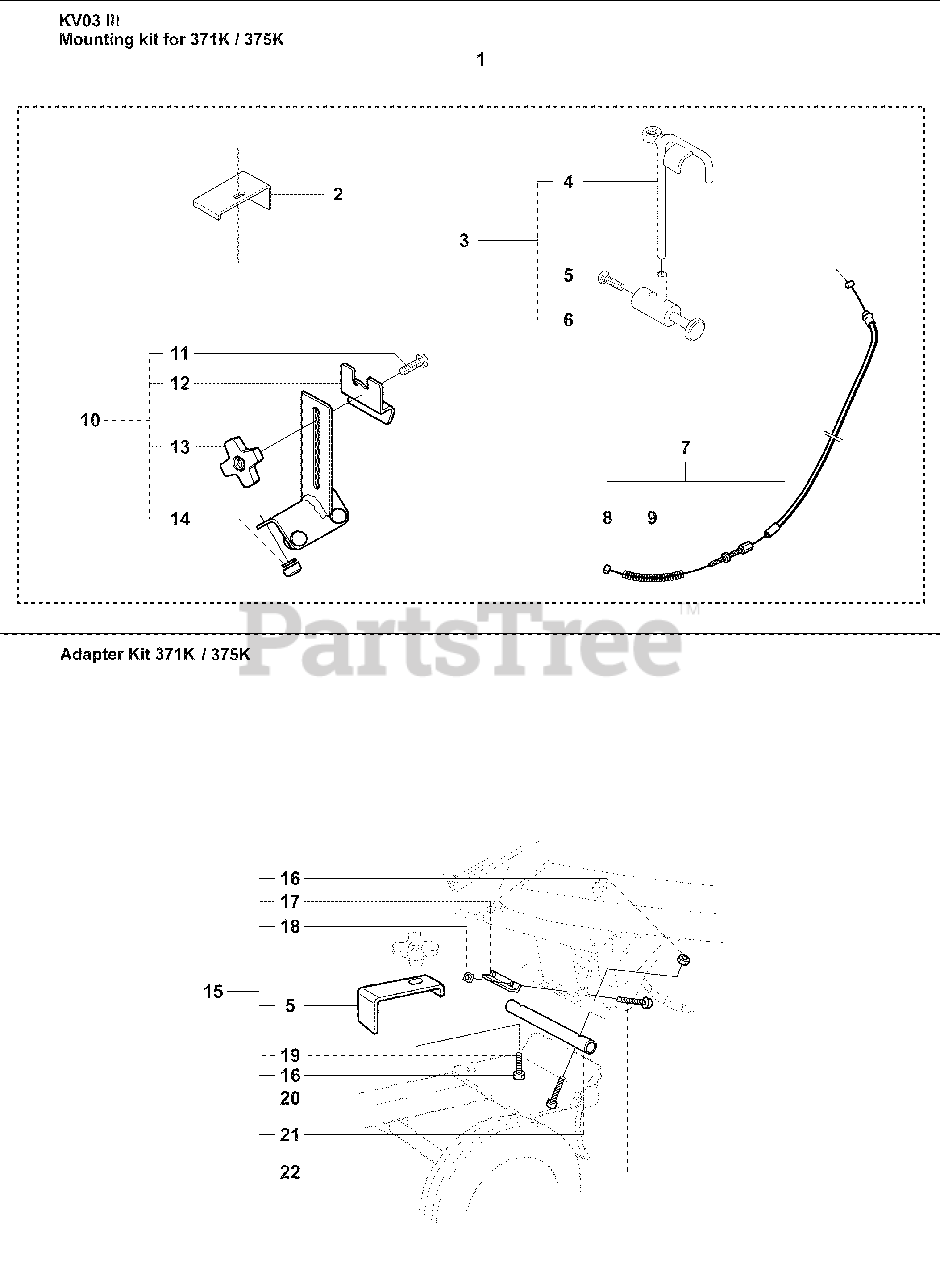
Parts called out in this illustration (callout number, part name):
1	ASSEMBLY KIT
2	PRESSURE PLATE
3	THROTTLE
7	THROTTLE WIRE
8	CABLE RETAINER
9	COMPRESSION SPRING
10	RETAINER
13	STEERING WHEEL
15	BRACKET
16	NUT
21	SPACER TUBE
